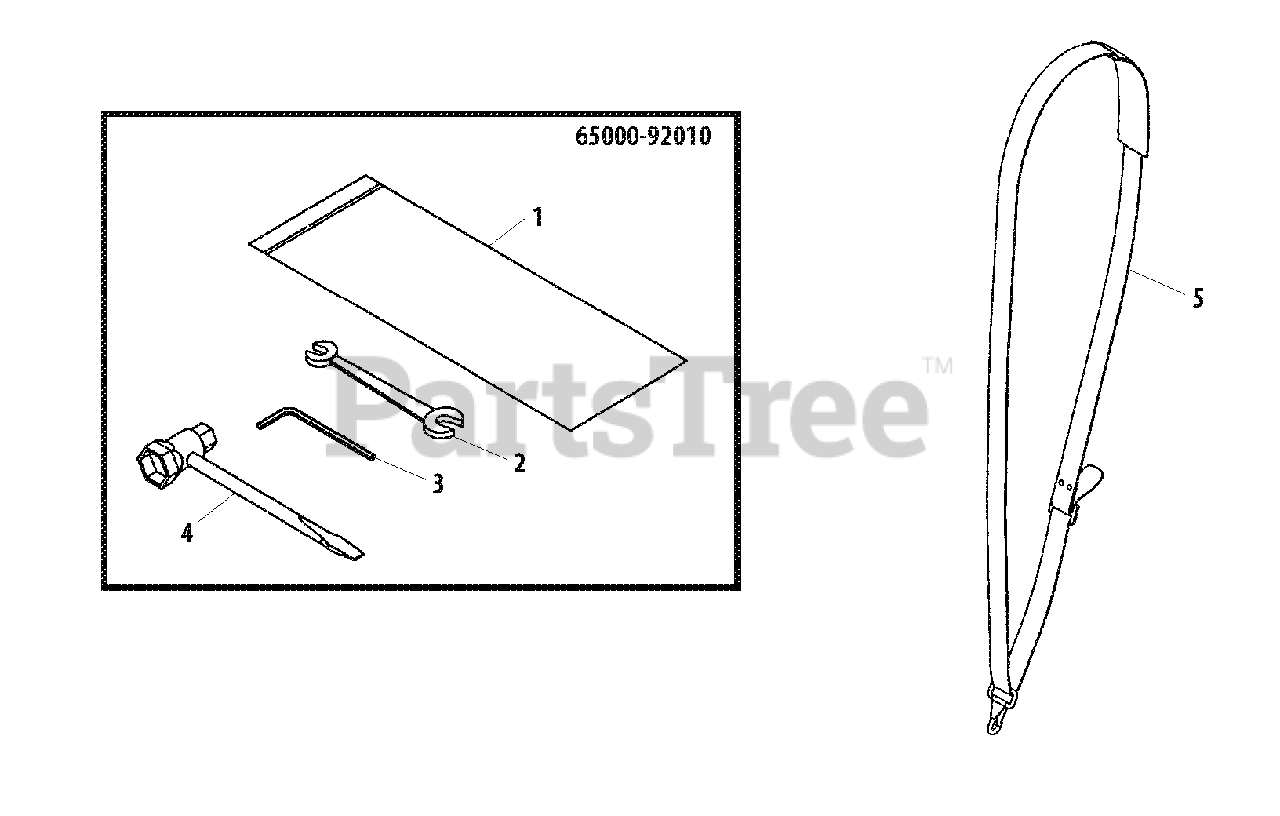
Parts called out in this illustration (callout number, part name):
1	BAG, TOOL
2	SPANNER 8×10
3	WRENCH, ALLEN 4 MM
4	T-WRENCH
5	HARNESS ASSY
65000-92010	SERVICE TOOL KIT
